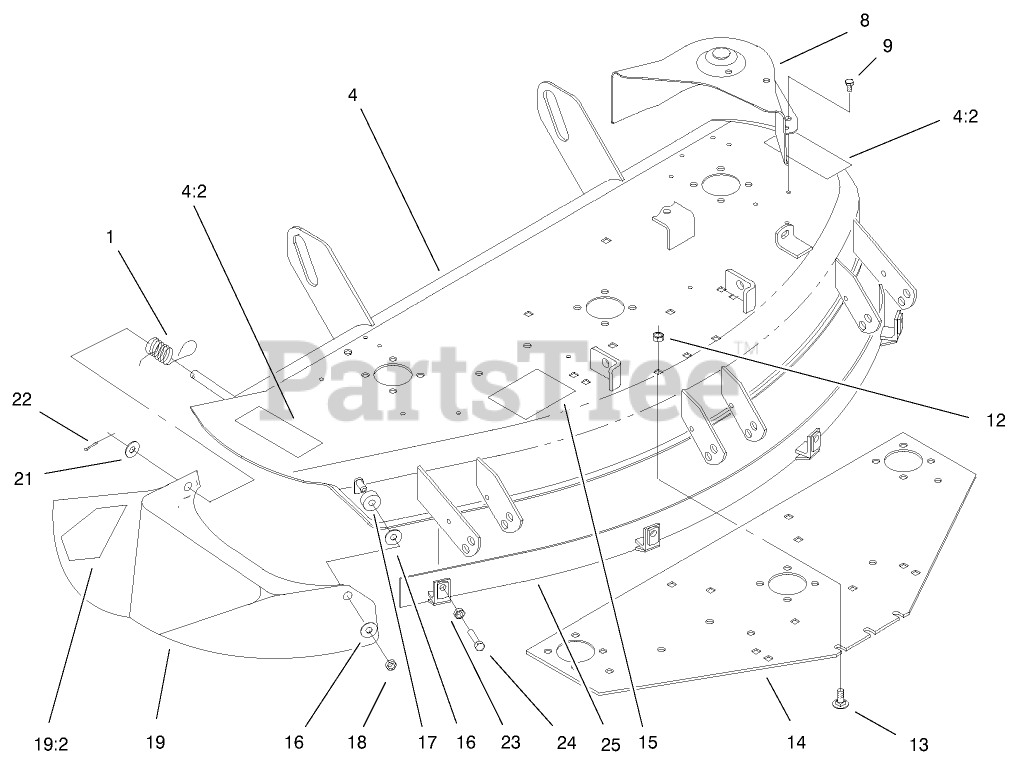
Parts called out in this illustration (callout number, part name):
1	SPRING-DEFLECTOR
4	DECK ASM
4:2	DECAL-DANGER
8	COVER-BELT
9	SCREW-HHFTF
12	NUT-LOCK, NI
13	SCREW-CARR
15	DECAL-BELT INSTALLATION
16	WASHER
17	BUSHING-PIVOT
18	NUT-HJ
19	CHUTE ASM
19:2	DECAL-DANGER
21	WASHER-FLAT
22	PIN-COTTER
23	NUT-JAM
24	SCREW - HHCS
25	Shield-Front
